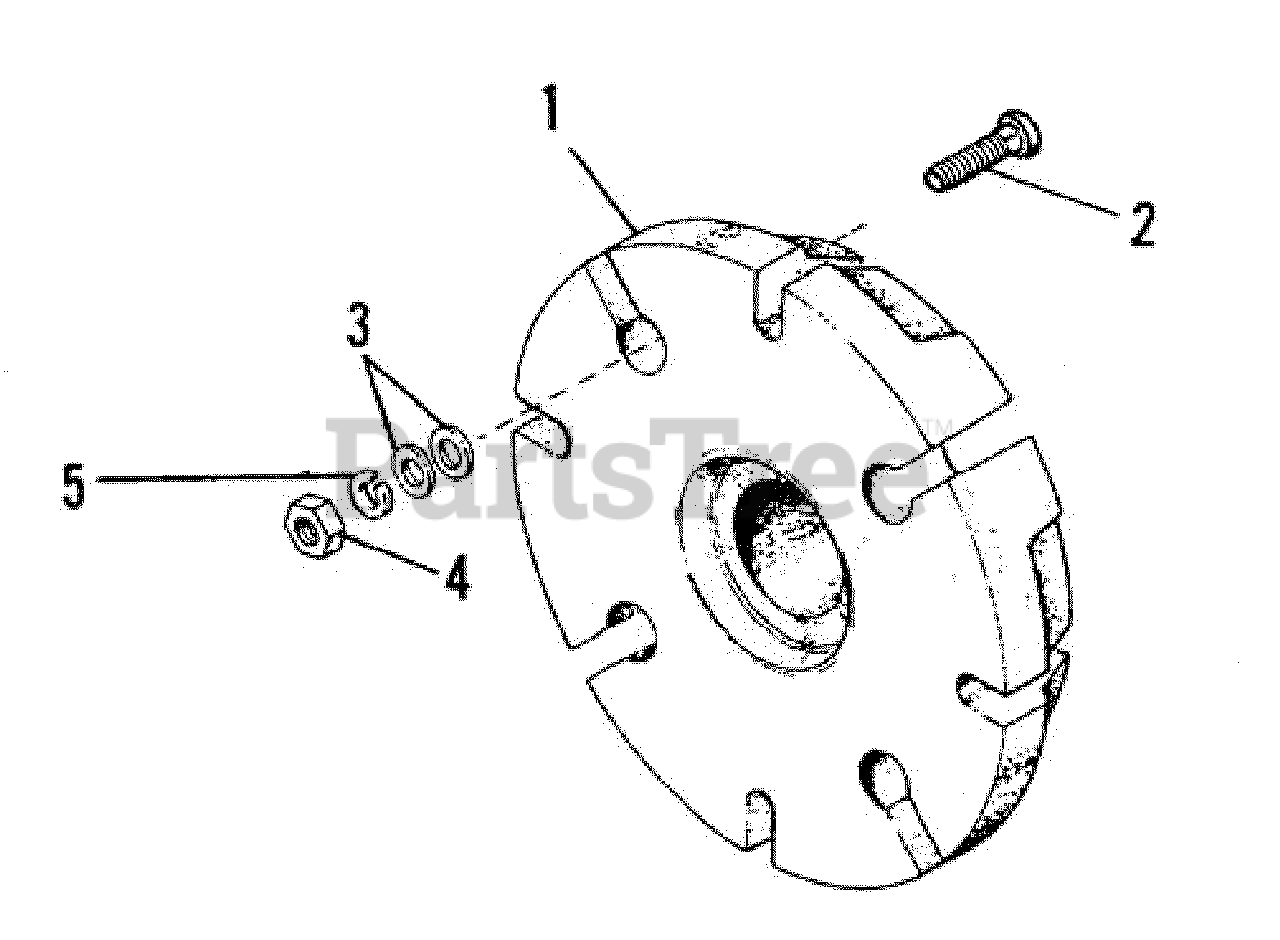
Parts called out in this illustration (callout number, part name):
1	WEIGHT, Wheel
2	BOLT, Carriage, 1/2-13 x 3-1/2
3	WASHER, Plain, 1/2
4	NUT, Full Hex Lock, 1/2-13
5	LOCKWASHER, 1/2
